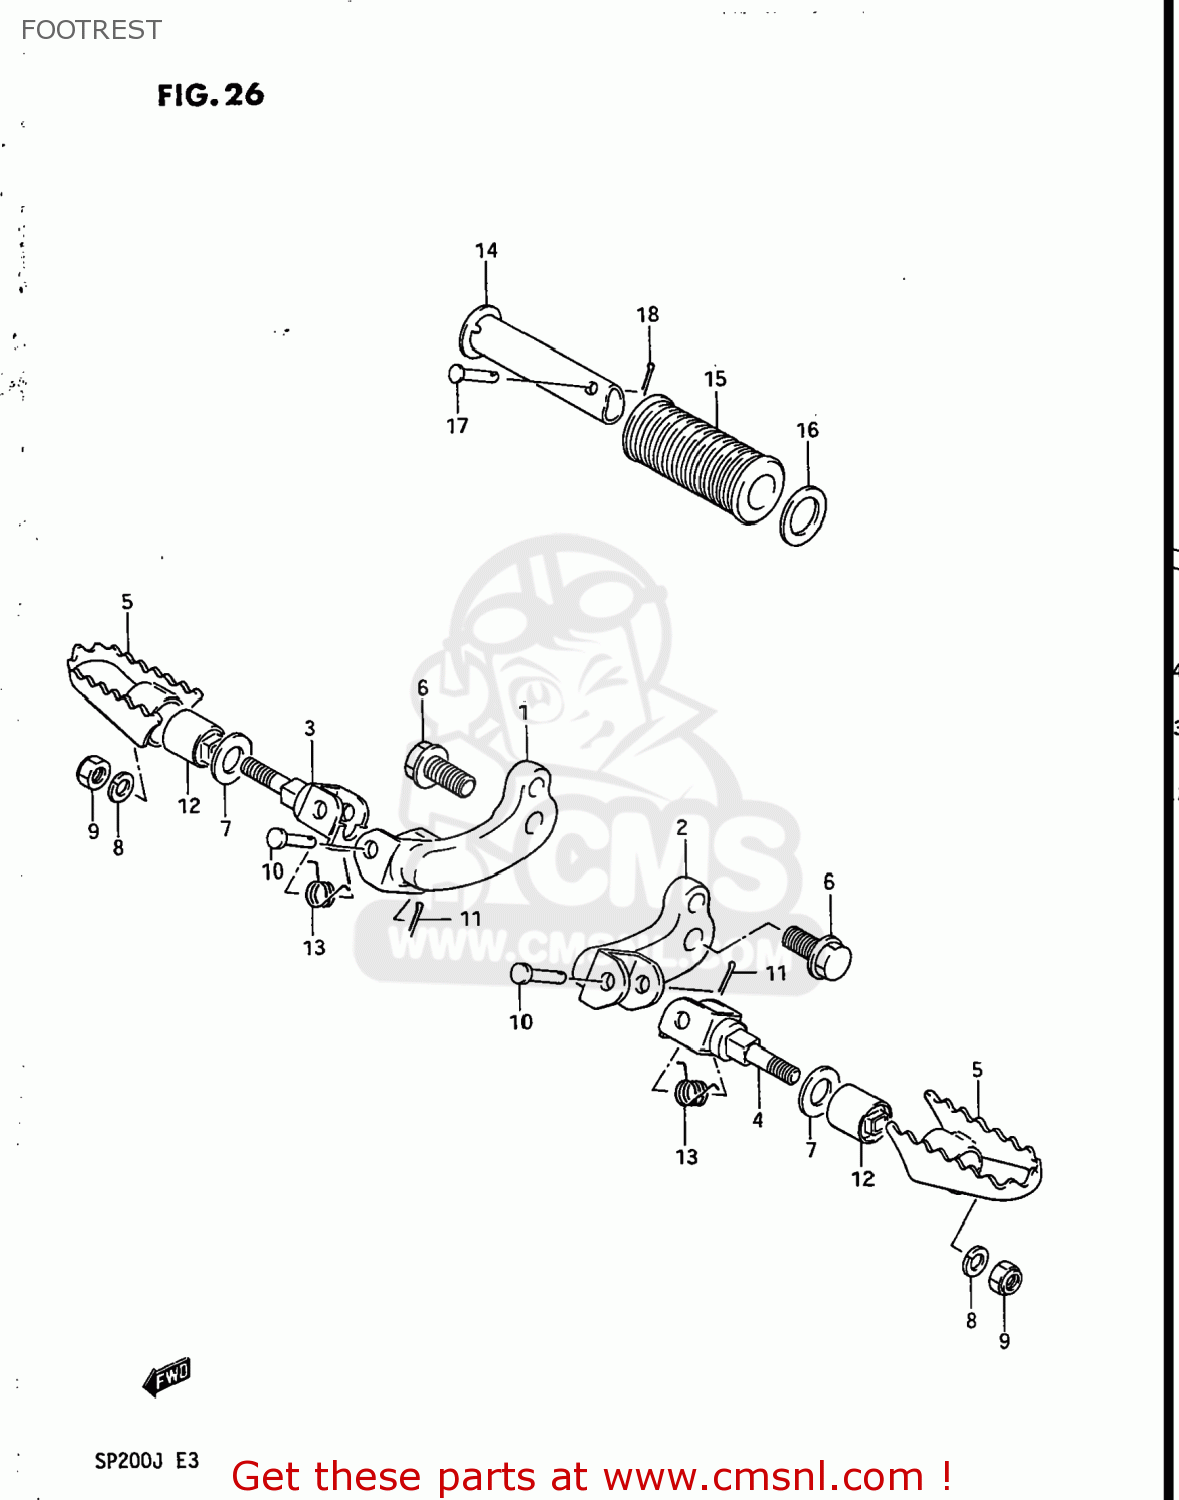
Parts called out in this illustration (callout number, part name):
1	BAR,FR FOOTREST,R
2	BAR,FR FOOTREST,L
3	BRACKET,FRONT FOOTREST
4	HOLDER COMP,FRONT FOOT
5	FOOTREST,FR
6	BOLT
7	WASHER
8	WASHER,LOCK
9	NUT
10	PIN
11	PIN
12	BUSH
13	SPRING
14	BAR,FOOTREST RUBBER
15	RUBBER,PILLION FOOTREST
16	WASHER (19.5X32X2)
17	PIN
18	PIN 20X20
